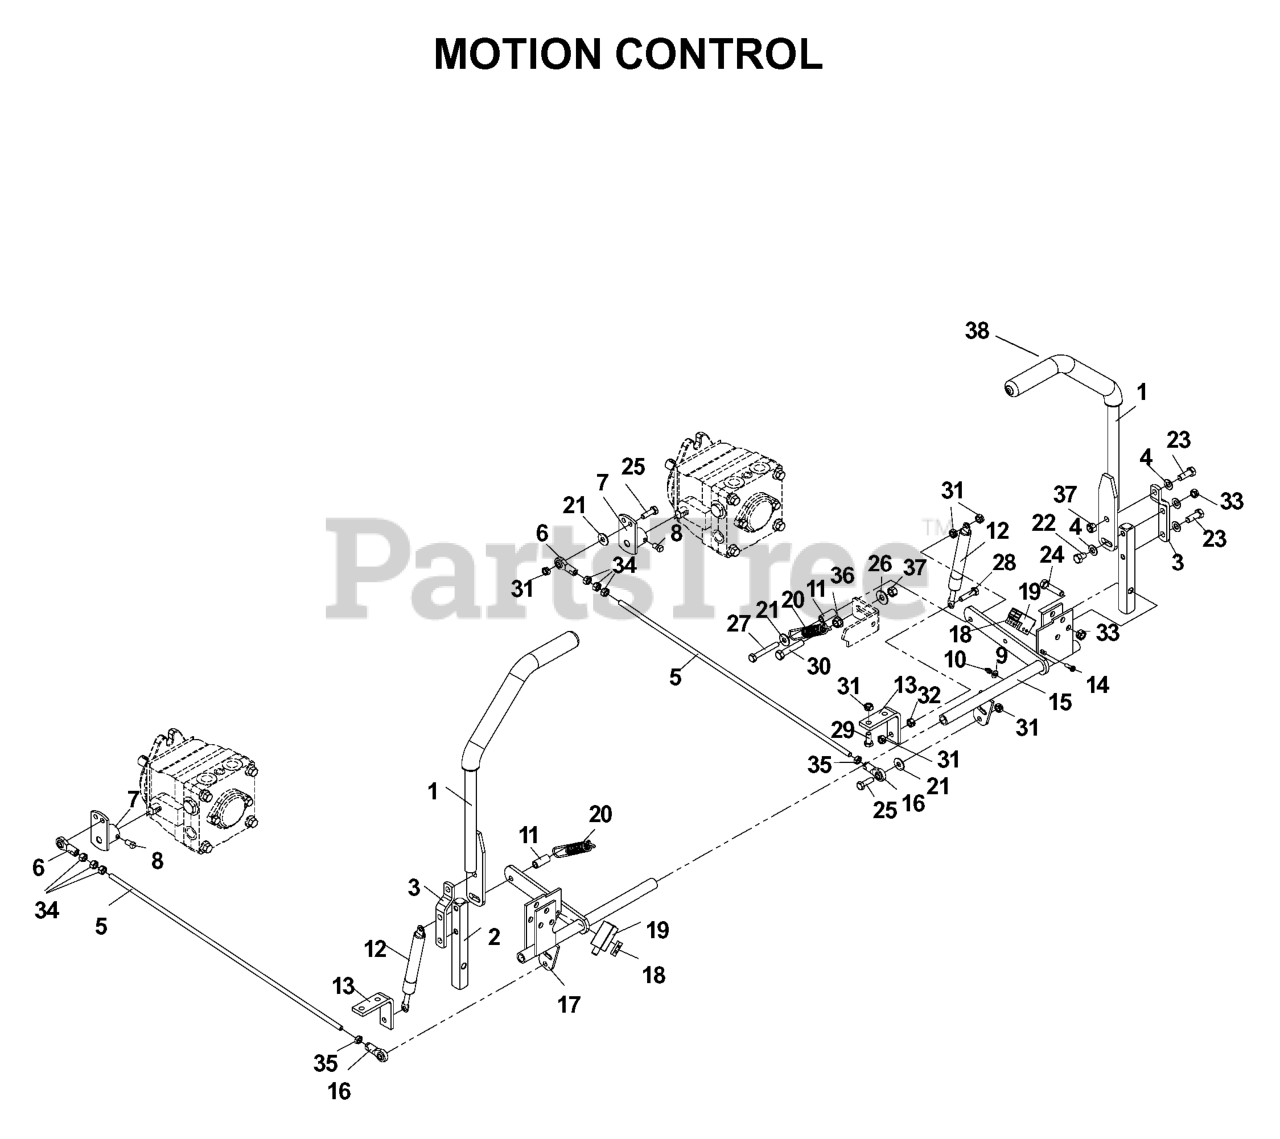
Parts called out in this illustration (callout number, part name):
1	HANDLE ASM
2	CONTROL ARM
3	CONTROL LEVER EXT
4	WASHER, 3/8 DISC SPRING SPEC
5	PUMP LINKAGE BAR
6	BALL JOINT, RIGHT HANDED
7	PUMP LEVER
8	5/16C X 5/8 "V" POINT
10	ZERK
13	L BRACKET-PAINTED
14	SCREW #10-24 X 5/8
15	CONTROL WELDMENT LT
16	BALL JOINT, LEFT HANDED
17	CONTROL WELDMENT RT.
18	TAPPED PLATE
21	WASHER 5/16 FLAT
22	BOLT, HCS 3/8-16X1-3/4
23	HCS 3/8-16X1.GRD.5.ZD
24	HCS 3/8C X 1 1/2
25	HCS 5/16C X 1
26	WASHER 3/8 FLAT
27	TAP BOLT 5/16C X 2 1/4
28	HCS 5/16C X 1 1/4
29	HCS 5/16C X 3/4
30	HCS 3/8C X 2
31	NUT 5/16C CENTERLOCK
32	NUT 5/16C WHIZ
33	NUT 3/8C CENTERBLOCK
35	NUT 5/16F LEFTHAND
36	NUT 3/8C WHIZ
37	NUT 3/8-16 NYLOC
